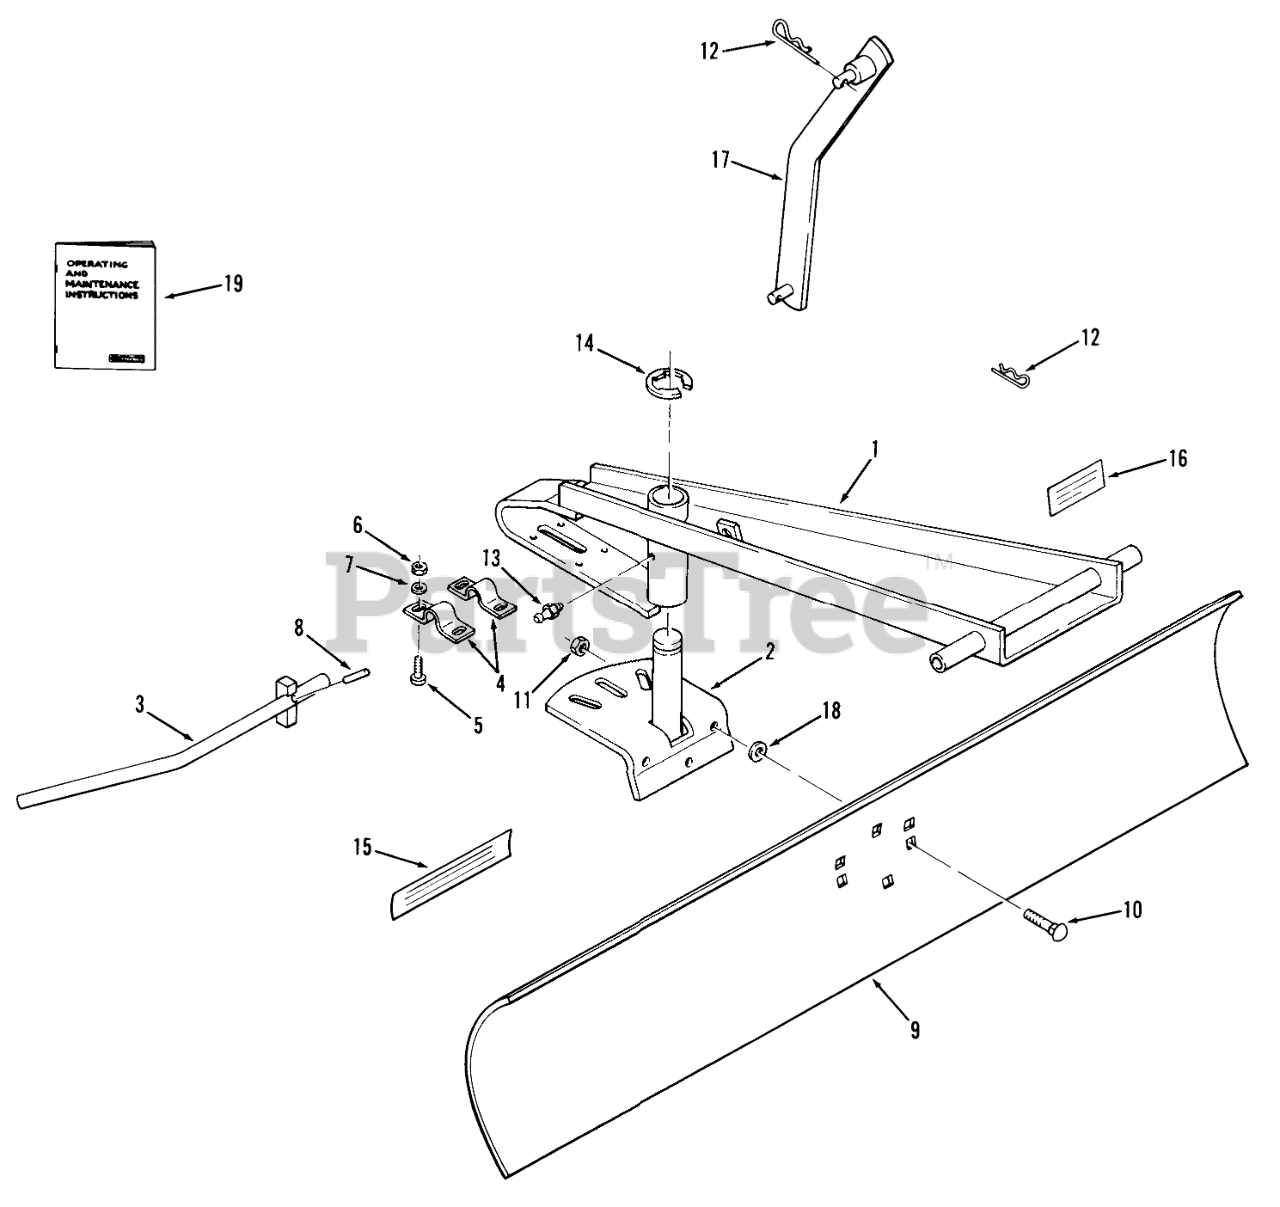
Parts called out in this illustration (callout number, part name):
1	Frame Assembly
2	Blade Support
3	Rod-Angle Adjustment
4	Bracket
5	Screw
6	Nut
7	WASHER
8	PIN-ROLL
9	Blade
10	Bolt
11	Nut
12	Hairpin
13	Zerk
14	E RING
15	DECAL-WHEEL HORSE
16	Caution Decal
17	Lift Link
18	Washer
19	Operating and Maintenance Instructions
